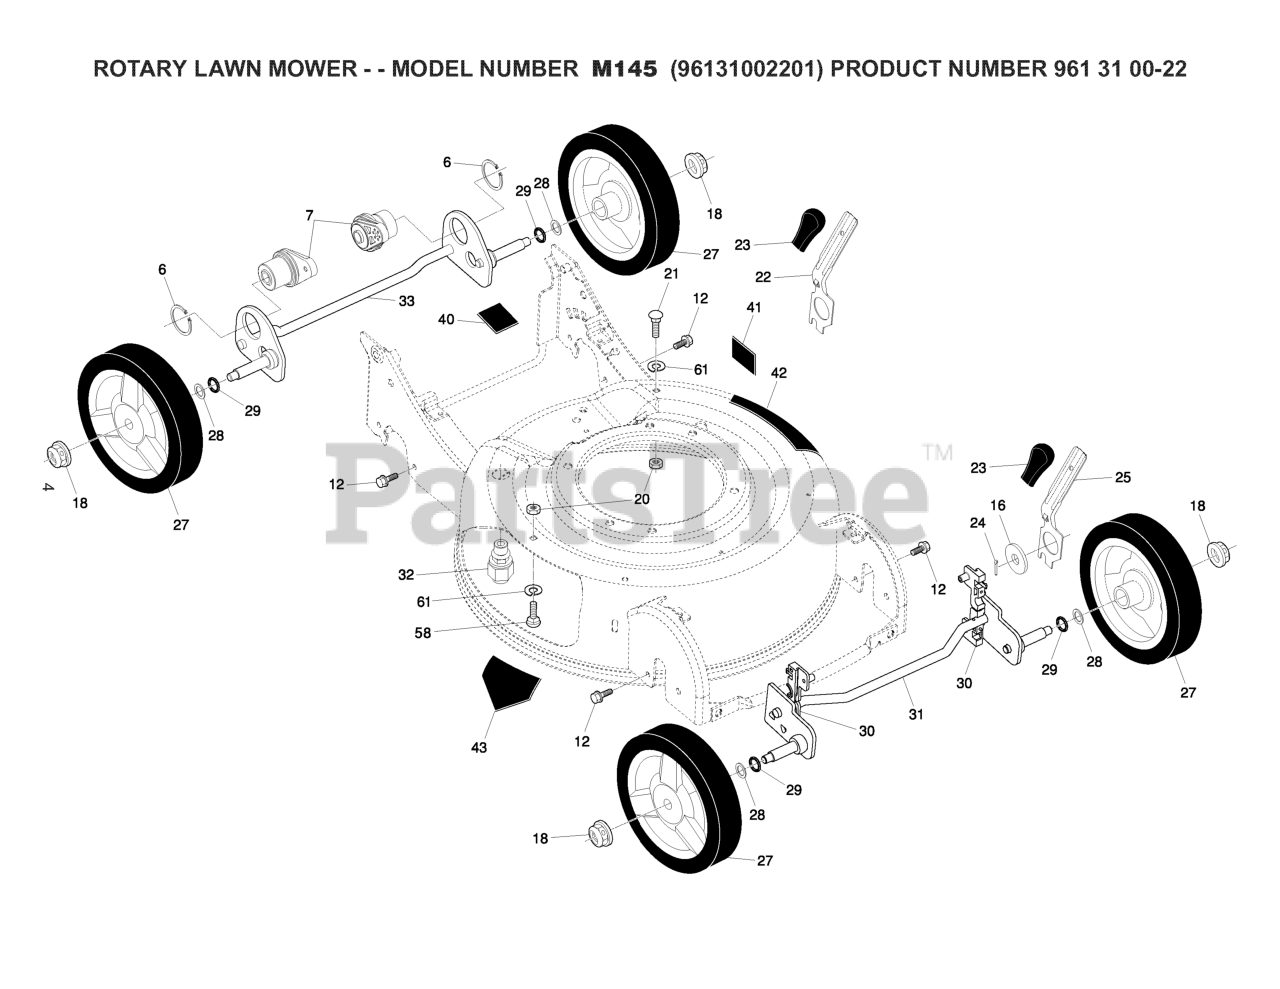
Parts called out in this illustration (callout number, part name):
6	RETAINING RING (2 2)(3 2)
18	NUT.HEX.FLANGE.3/8-16.LO(3 2)
20	NUT, HEX
21	BOLT.CARRIAGE.1/4-20 X 7/8
24	SPRING RETAINER
27	WHEEL & TIRES ASSY, FRONT
28	WASHER.FLAT.1/2
29	O-RING..070X.487.NEOPRENE
30	BUSHING.FRONT.TORQUE.S
33	AXLE.ASM.REAR.45CM.SP.BZP
43	DECAL.INTERNATIONL.CUTFINGER
58	BOLT.CARRIAGE.1/4-20 X 7/8
61	LOCKWASHER
